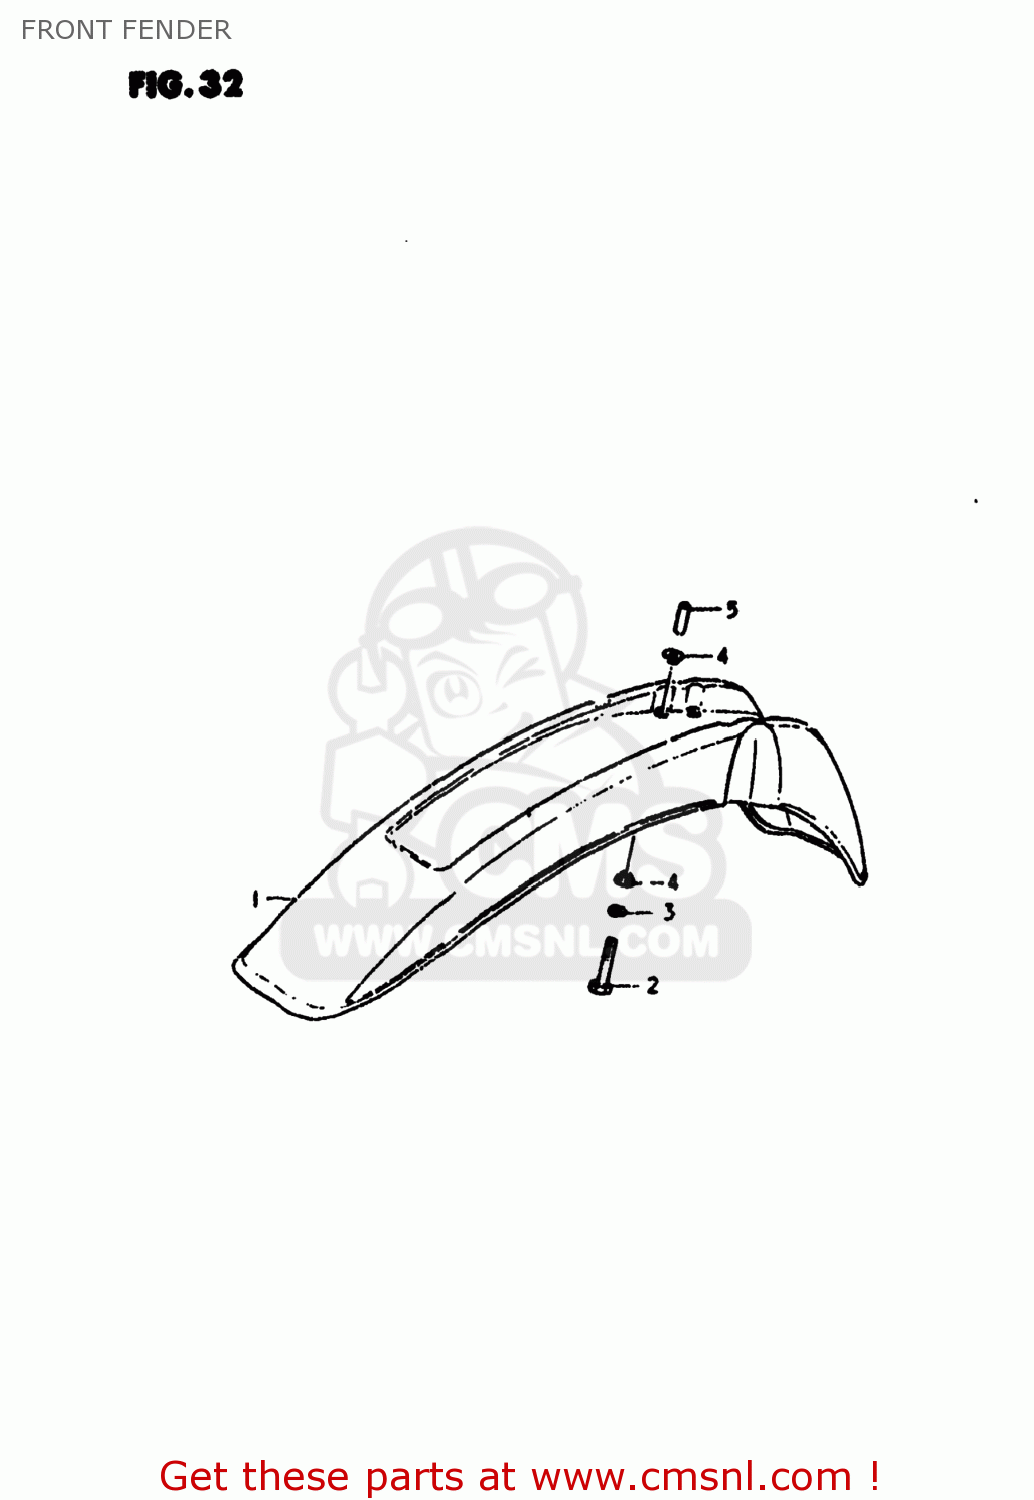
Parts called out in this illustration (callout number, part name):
1	FENDER,FRONT
2	BOLT
3	LOCK WASHER
4	SPACER
5	SPACER (6.8X10X27.4)
